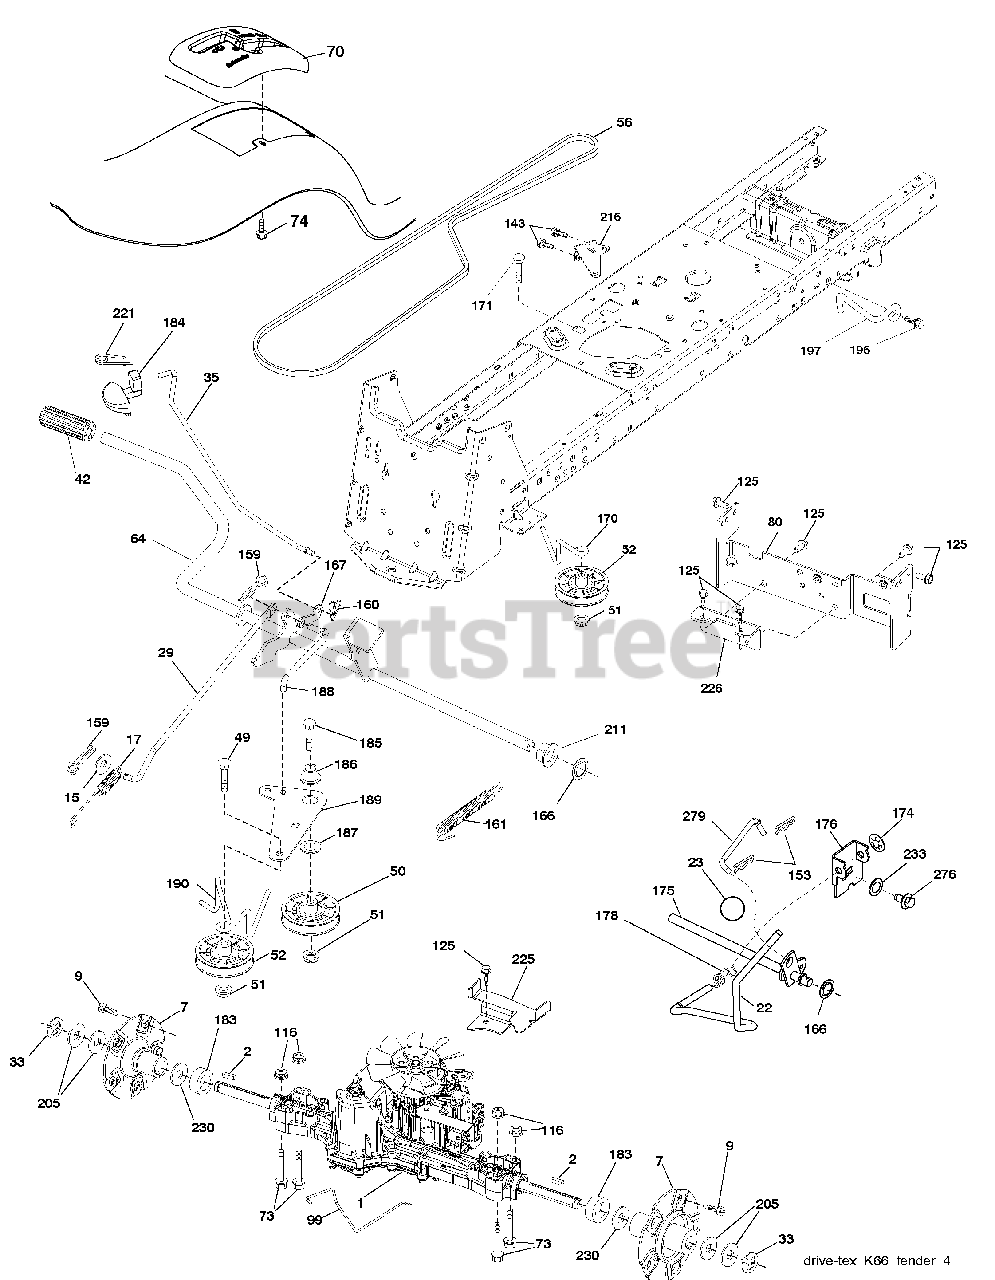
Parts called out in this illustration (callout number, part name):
1	Transaxle, TuffTorq K66 AD
2	Key
7	Hub Asm. Wheel
9	Bolt Hub Wheel
15	Washer 13/32 x 13/16 x 16 Ga.
17	Spring, Brake
22	Rod Shift
23	Knob
29	Rod, Brake
33	Ring E
35	Rod, Brake, Park
42	Cover, Foot Pedal
49	Bolt
50	Pulley Idler Flat
51	Lock Nut 3/8-16
52	Idler V-Groove 910" Offset
56	V-Belt, Drive
64	Shaft Asm. Pedal Brake Control
69	Washer 1 1/32 x 1 5/8 x 16 Ga.
70	Console Shift
73	Bolt Hex Flghd 5/16-18 Gr. 5
74	Screw Hx Wsh Hi-Lo 1/4 x 1/2 unc
80	Strap Torque
99	Rod Bypass
116	Nut Lock Hex Flange 5/16-18
125	Screw 5/16-18 x 3/4
143	Screw 5/16-18 x 1/2
153	Retainer Spring
159	Pin Cotter 1/8 x 3/4
160	Retainer Clip
161	Spring, Return, Clutch
166	Nut Push .625
167	Latch Brake Parking
170	Keeper Belt Centerspan
171	Bolt
174	Nut Push
176	Arm Clevis Rod Shift
178	Spring Shift
183	Spacer Axle
184	Handle Parking Brake
185	Bolt
186	Spacer Retainer
187	Washer
188	Link Clutch Ground Drive
189	Bellcrank Ground Drive
190	Keeper Bellcrank Ground Drive
196	Screw 3/8-16 x 1
197	Bracket Clutch Anti-Rotation
205	Washer 1-1/32 x 1-5/8 x 16 Ga.
211	Bushing Shaft
216	Bracket Pulley Idler
221	Retainer Spring Clip Handle
225	Keeper Belt Trans.
226	Bracket Mount Torque
230	Washer Thrust Axle
233	Washer Serrated
275	Shaft Asm. Shift
276	Bolt Fin. Hex 7/16-14 x 1 Gr. 5
279	Link Asm. Shift
